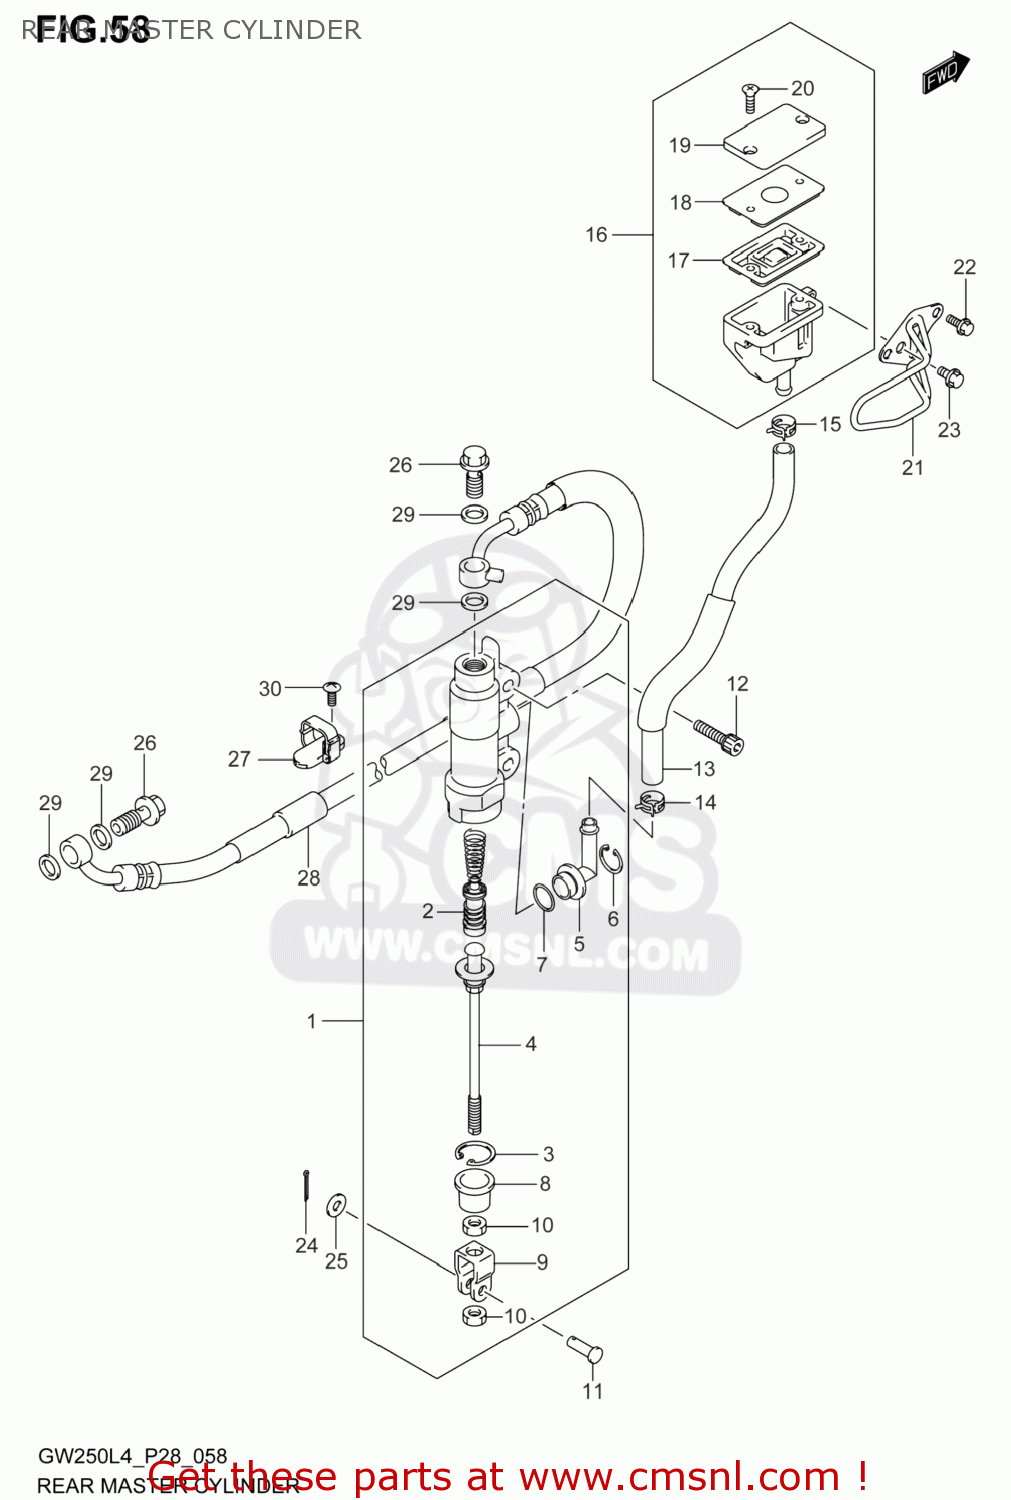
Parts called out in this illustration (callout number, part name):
1	CYLINDER ASSY,RR MASTER
2	PISTON/CUP SET
3	CIRCLIP
4	ROD,PUSH
5	CONNECTOR
6	CIRCLIP
7	O RING
8	BOOT
9	YOKE
10	NUT
11	PIN
12	BOLT
13	HOSE,RR RESERVOIR TANK
14	CLIP,RR RSVR TANK HOSE LWR
15	CLIP,RR RSVR TANK HOSE UPR
16	TANK ASSY,REAR RESERVOIR
17	DIAPHRAGM
18	PLATE,DIAPHRAGM
19	CAP
20	SCREW
21	GUARD,RR RESERVOIR TANK
22	BOLT
23	BOLT
24	PIN
25	WASHER
26	BOLT,BRAKE FLUID
27	GUIDE,RR BRAKE HOSE
28	HOSE,RR BRAKE
29	WASHER,BRAKE FLUID
30	SCREW
